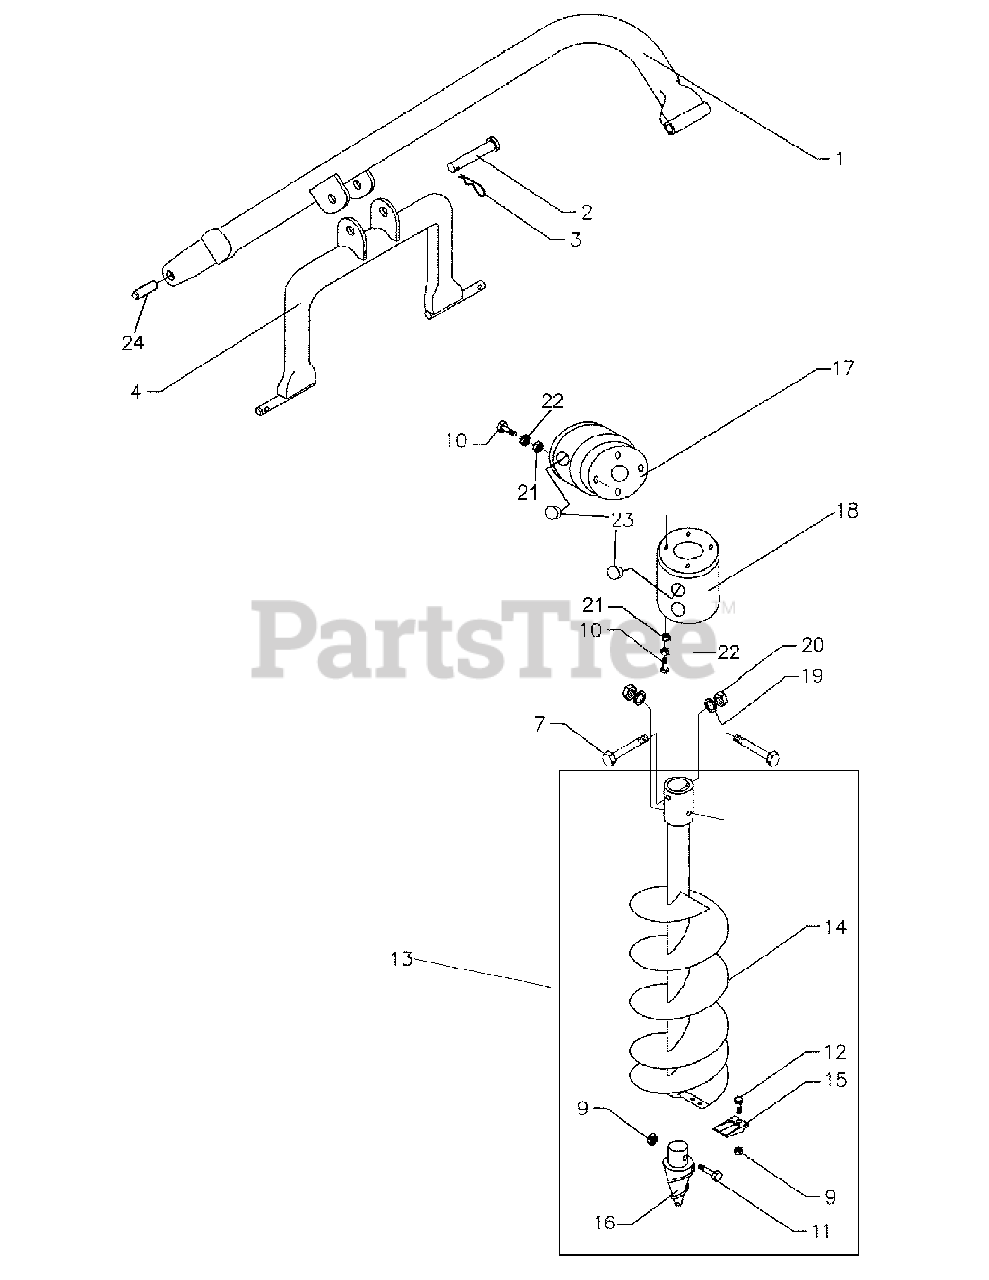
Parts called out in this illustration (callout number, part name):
1	Boom Assembly PHD200
2	Pin 1"x6"
3	Lynch pin
4	Yoke PHD200
7	Bolt M12x90
9	Stover nut M12 (9" Auger)
10	Bolt 5/16"x¾"
11	Bolt M12x80
12	Bolt M12x30 (9" Auger)
13	9" Double flighted auger complete 48"
15	Cutting knife (9" Auger)
16	Auger point - standard
16	Auger point - fish tai l
17	Gearbox guard
18	Auger guard
19	Lock washer Ø12
20	Hex nut M12
21	Flat washer 5/16"
22	Lock washer 5/16"
23	Cap
24	Bushing cat. 2-1
